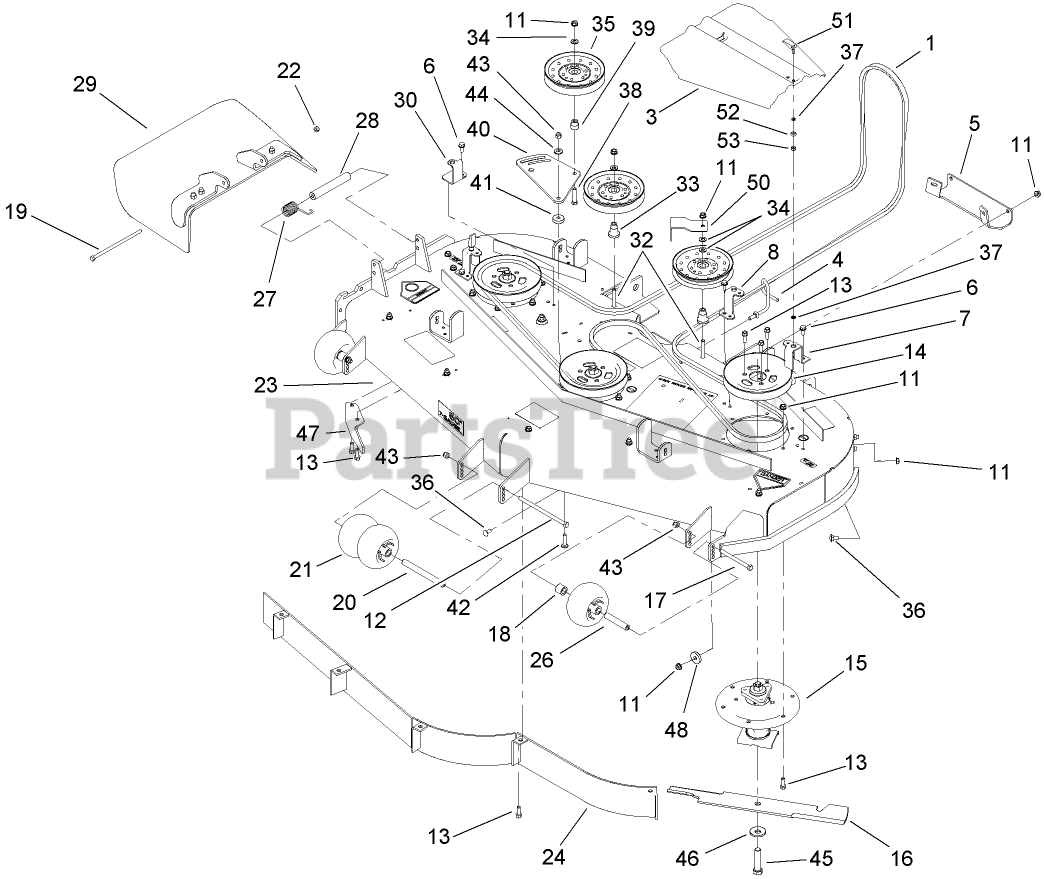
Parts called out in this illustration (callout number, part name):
3	COVER-BELT
4	GUIDE-BELT
5	PLATE-SKID
6	SCREW-HWHTF
8	BRACKET-COVER, TALL
11	NUT-HHF, WHIZ
12	SCREW-HH
14	PULLEY
15	SPINDLE ASM
16	BLADE-HI FLOW
17	SCREW-HH
18	TUBE-SPACER
19	SCREW-HH
20	SPACER-WHEEL
21	ROLLER-SCALP, ANTI
22	NUT-LOCK, NI
23	DECK DECAL ASM
24	BAFFLE ASM
26	TUBE-SPANNER
27	SPRING-TORSION
28	SPACER
29	RUBBER DEFLECTOR ASM
32	SCREW-CARR
33	MOUNT-PULLEY
34	WASHER-FLAT
36	SCREW-CARR
37	WASHER
38	SCREW-HH
39	BUSHING-IDLER
40	PLATE-IDLER
41	SPACER
42	SCREW-CARR
43	NUT-LOCK, NI
44	WASHER-BELLEVILLE
45	SCREW-CAP
46	WASHER-BLADE BOLT, HEAVY
47	BAFFLE-DISCHARGE
48	WASHER
50	GUIDE-BELT
51	HANDLE-LATCH, SWELL
52	BUSHING-LATCH, SWELL
53	NUT-LOCK, HH
